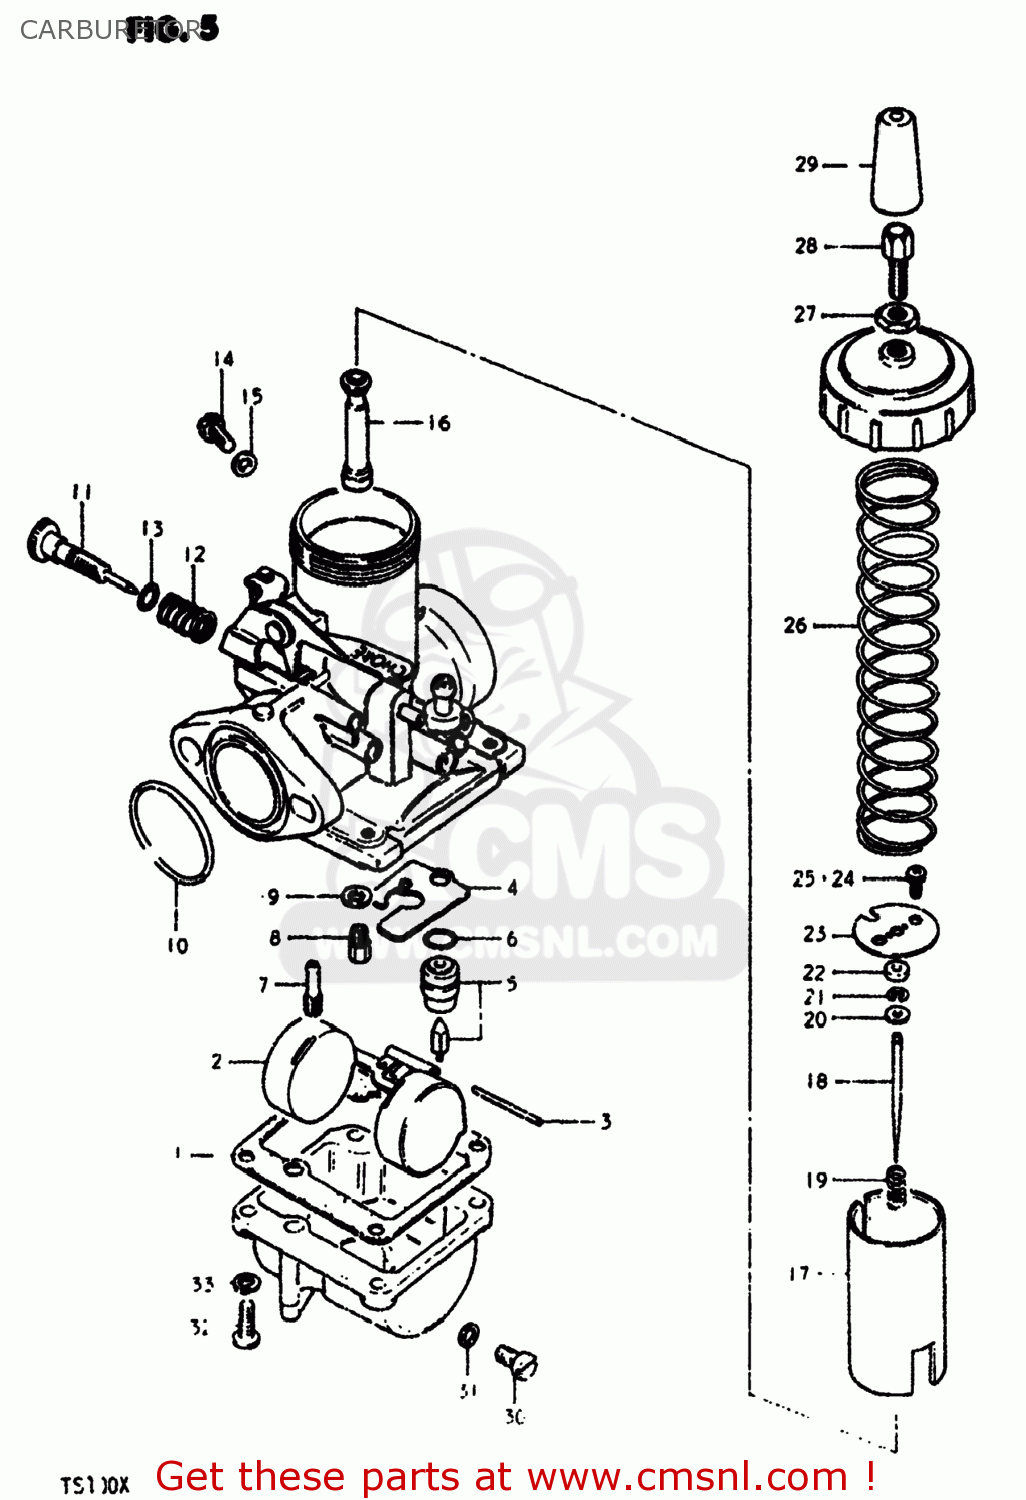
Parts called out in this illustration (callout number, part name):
1	GASKET,FLOAT CHAMBER (NAS)
2	FLOAT
3	PIN,FLOAT
4	PLATE
5	VALVE ASSY,NEEDLE
6	GASKET,VALVE SEAT (NAS)
7	JET,PILOT(17.5)
8	JET,MAIN(115)
9	WASHER
10	O RING
11	SCREW,THROTTLE STOP
12	SPRING,PILOT
13	O-RING
14	BOLT
15	GASKET,THRO VALVE INSPECTION (NAS)
16	JET,NEEDLE
17	VALVE,THROTTLE
18	NEEDLE JET
19	SPRING
20	WASHER,JET NEEDLE
21	CLIP
22	RING
23	PLATE,THROTTLE VALVE
24	LOCK WASHER
25	SCREW
26	SPRING,THROTTLE VALVE
27	NUT
28	ADJUSTER,CABLE
29	CAP
30	PLUG
31	GASKET,DRAIN,PLUG (NAS)
32	SCREW
33	LOCK WASHER
